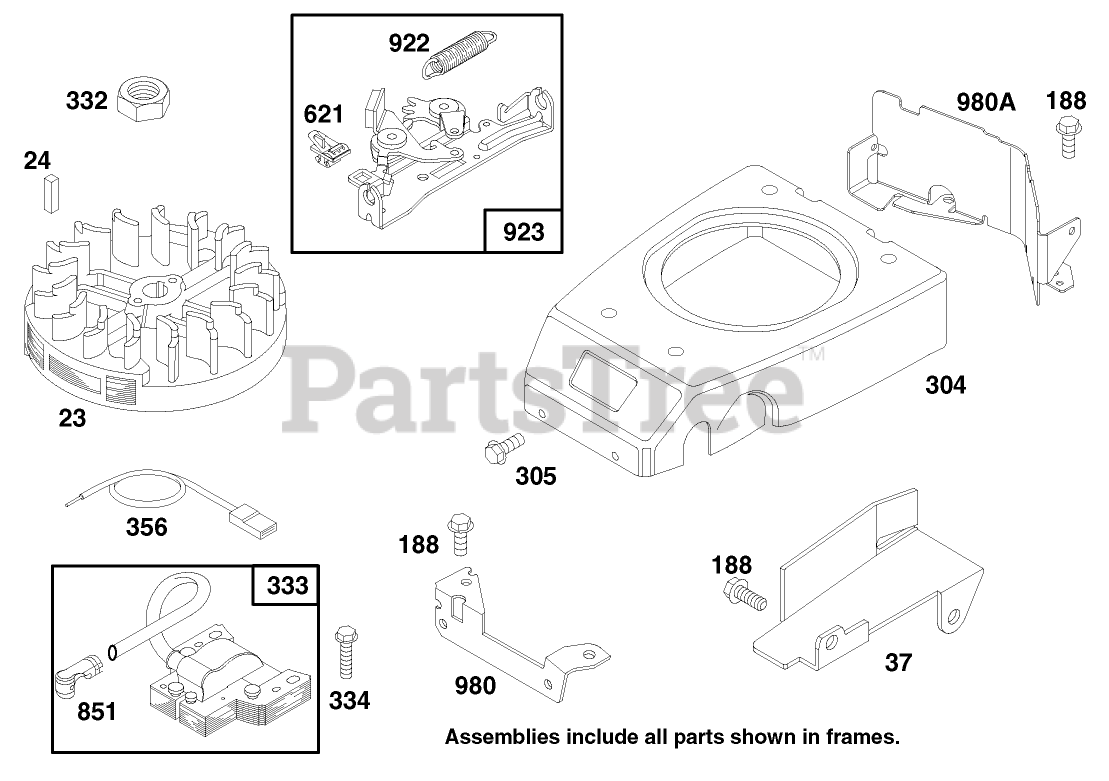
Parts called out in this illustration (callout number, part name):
24	KEY - FLYWHEEL
304	HOUSING - BLOWER
305	SCREW - HEX HEAD
332	NUT - HEXAGON
356	WIRE - GROUND
621	STOP SWITCH
980	Bracket-Blower Housing
980A	BLOWER HSG BRACKET
